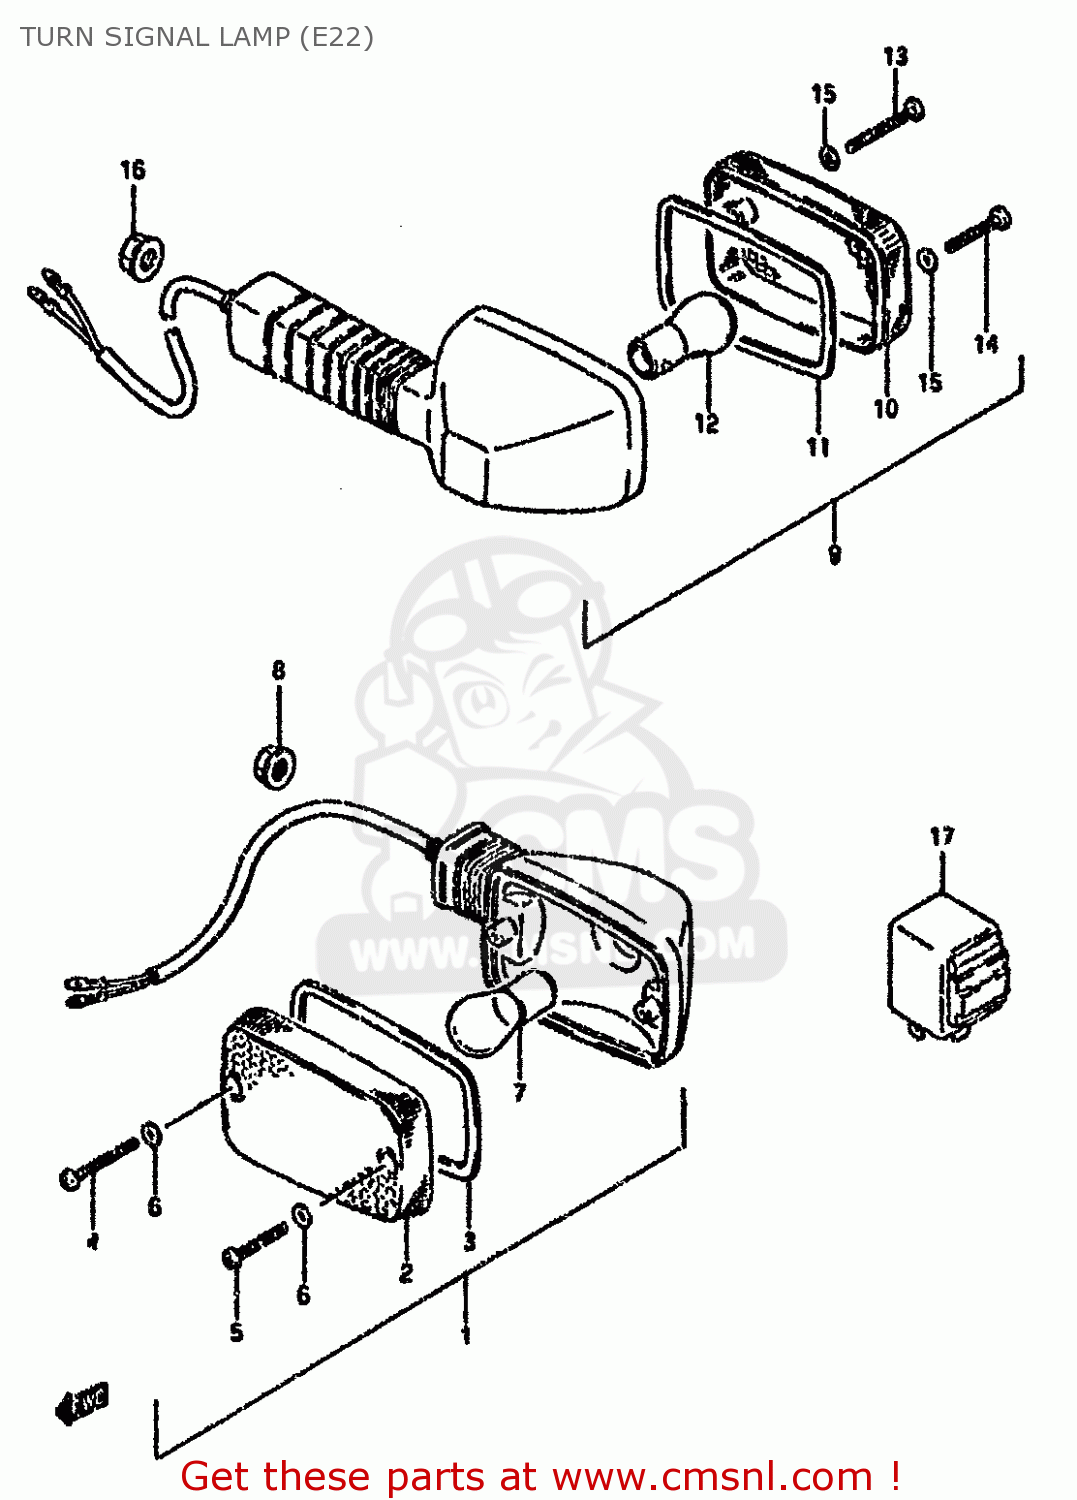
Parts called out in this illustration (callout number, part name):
1	LAMP ASSY,FR
2	LENS,FR
3	GASKET (NAS)
4	SCREW,TURN SIG LENS FITTING
5	SCREW
6	GASKET (NAS)
7	BULB(12V21W)
8	NUT
9	LAMP ASSY,RR
10	LENS,RR
11	GASKET (NAS)
12	BULB(12V21W)
13	SCREW,TURN SIG LENS FITTING
14	SCREW
15	GASKET (NAS)
16	NUT
17	RELAY ASSY,TUR
